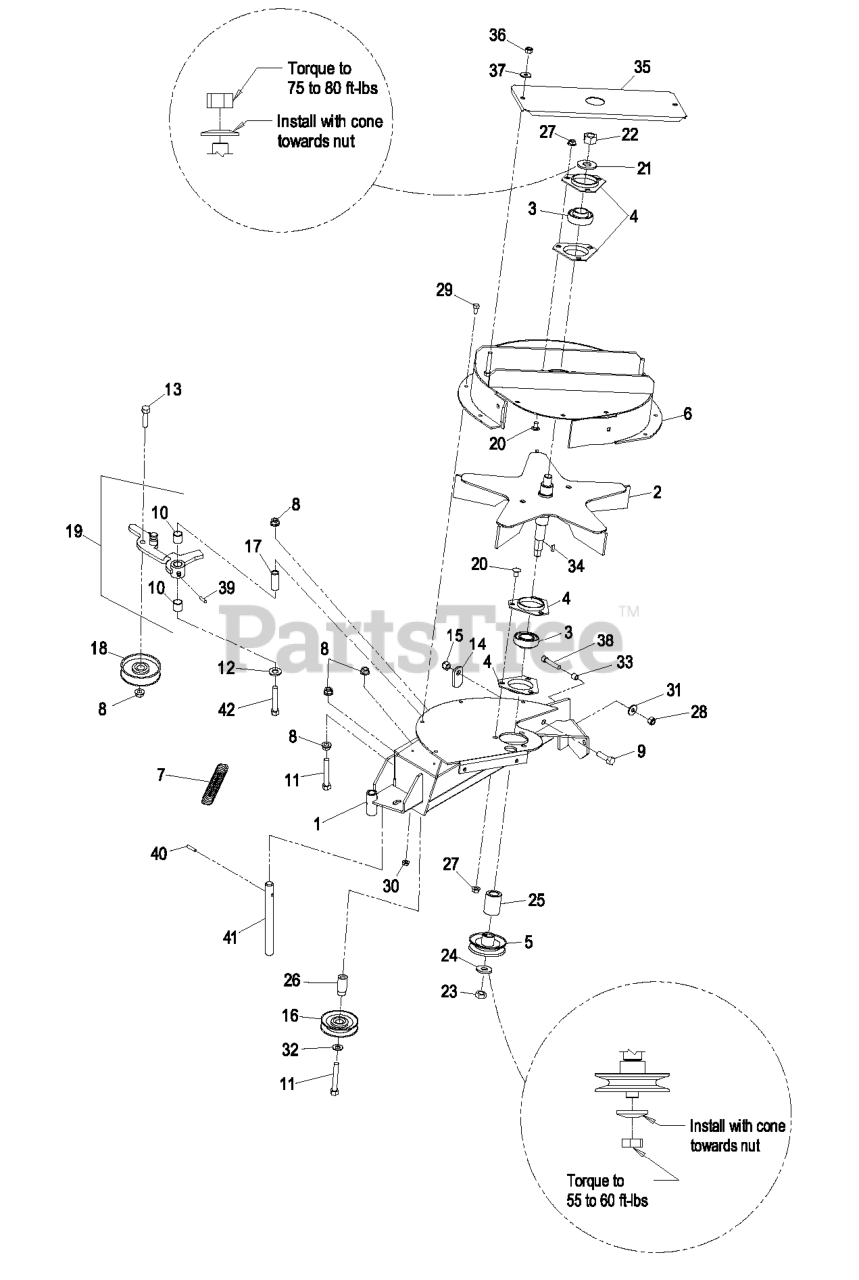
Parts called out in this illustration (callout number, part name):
1	WLD, BLOWER MOUNT
2	IMPELLER
3	BEARING
4	HOUSING-FLANGE
5	SHEAVE-BLOWER
6	ASM,UPPER HOUSING
7	SPRING-IDLER
8	NUT-HHF, WHIZ
9	SCREW-HH
10	BUSHING
11	BOLT-CARR
12	WASHER-FLAT
13	SCREW-HH
14	LATCH-CATCHER, GRASS
15	NUT-LOCK, NI
16	IDLER-INSIDE
17	BUSHING-PIVOT, IDLER
18	IDLER-FLAT
19	ASM, IDLER ARM - SERVICE
20	SCREW-CARR
21	WASHER-SPRING
22	NUT-HEX
23	NUT-JAM
24	WASHER-SPRING
28	NUT-HEX
29	SCREW-HH
31	WASHER-SPRING
32	WASHER-FLAT
33	BUSHING, LOCATOR
34	KEY-WOODRUFF
35	ASM, BEARING COVER
36	NUT-LOCK, NI
37	WASHER-FLAT
38	SCREW-HSH
39	FITTING-GREASE
40	PIN-ROLL
41	SHAFT-CATCHER, GRASS
42	SCREW-HSBH
